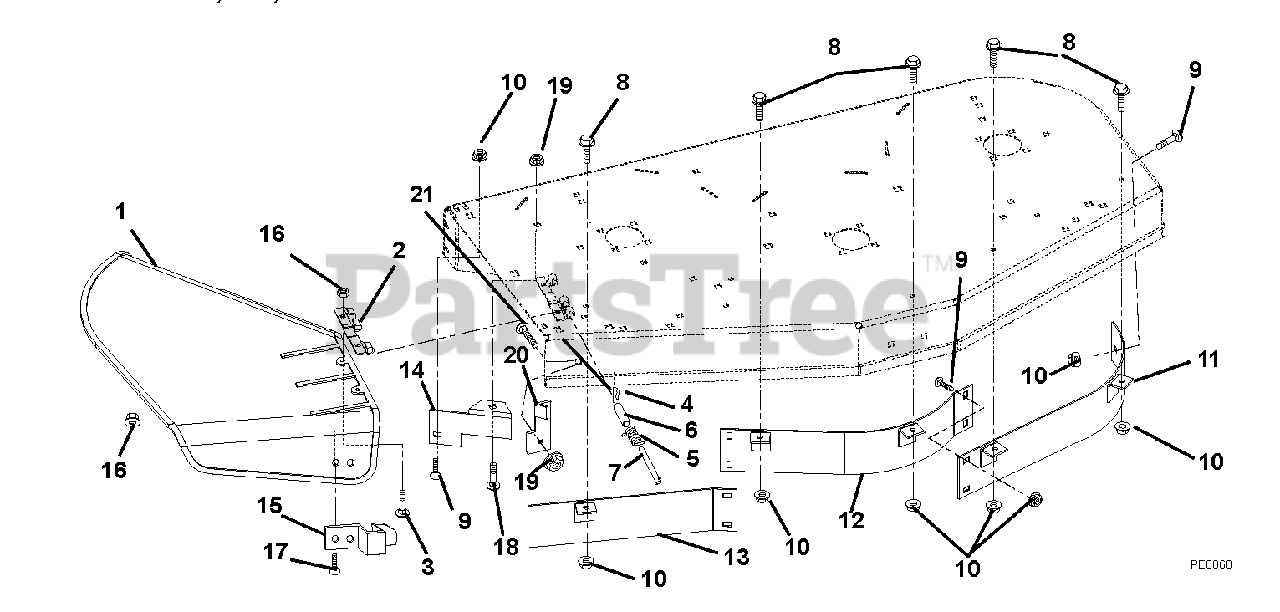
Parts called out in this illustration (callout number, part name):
1	Deflector, Chute
2	Hinge, Plate
3	Bolt, Round Head Square Neck .25-20 x .75 Grade 5
4	Pin, Internal .08 x .18 x 1.18
5	Spring, Torsion .095 x .50 x 1.00
6	Bushing, Sleeve
7	Pin, Clevis
8	Bolt, Serrated Hex Flange Washer Head .31-18 x .75
9	Bolt, Round Head Square Neck .31-18 x .75
10	Nut-.312-18 Flange Nyloc
11	Weldment, Upper Left Baffle-40" (400)
12	Weldment, Upper Center Baffle-40" (400)
13	Weldment, Upper Right Baffle-40" (400)
14	Deflector, 40" (400)
15	Flat Spring
16	Nut, Locking Top Flange .25-20
17	Bolt, Round Head Square Neck .25-20 x .50 Grade 5
18	Bolt, Round Head Square Neck .38-16 x 1.00 Grade 5
19	Nut, Flange Nyloc .375-18
20	Bracket, Chute Lock
21	Bolt, Round Head Square Neck .38-16 x 1.50
